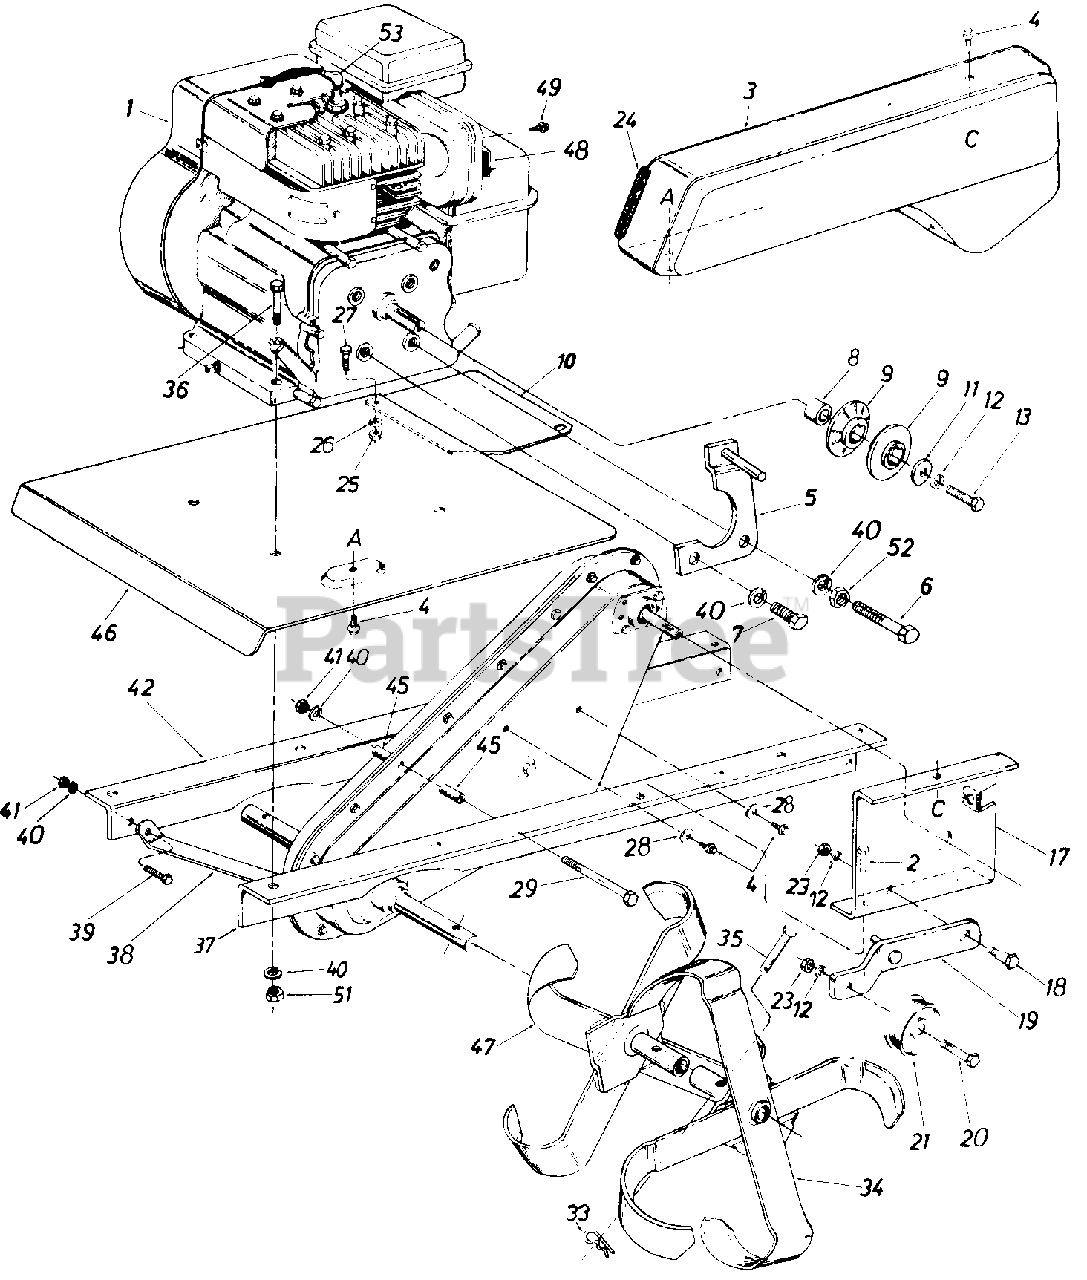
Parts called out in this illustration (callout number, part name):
1	Engine
2	Hex Self-Tap Scr. 5/16-24 x .5"
3	Belt Cover
4	Hex Self-Tap Scr. 1/4-20 x .5"
5	Belt Keeper Brkt. Ass'y.
6	Hex Bolt 5/16-24 x 2.25" Lg. (Gr. 5)
7	Hex Bolt 5/16-24 x .62" Lg. (Gr. 5)
10	Tine Shield Extension
11	Fl-Wash. 318" I.D. x 1.25"
12	L-Wash. 318" I.D.*
13	Hex Bolt 3/8-24 x 1.00" Lg.
17	Idler Mounting Brkt.
18	Shld. Bolt
19	Idler Bracket Ass'y.
20	Hex Bolt 3/8-16 x 1.5" Lg.
21	Idler Pulley
23	Hex Jam Nut 3/8-16 Thd.
24	Trim Strip-3"
25	Hex Nut 1/4-20 Thd.
26	L-Wash. 1/4" I.D.
27	Hex Bolt 1/4-20 x .62 Lg.*
28	Bell-Wash. .26 I.D. x .75 O.D.
29	Hex Bolt 5/16-18 x 3" Lg.*
33	Hairpin Cotter
34	See Tine Chart
36	Hex Bolt 5/16-18 x 1.5" Lg.*
37	Frame Rail-L.H.
38	Front Brace Brkt.
39	Hex Bolt 5/16-18 x .75" Lg.*
40	L-Wash. 5/16" I.D.*
41	Hex Cent. L-Nut 5/16-18 Thd.
42	Frame Rail-R.H.
47	See Tine Chart
49	Hex Self-Tap Scr. #8-32 x .38"
51	Hex Nut 5/16-18 Thd.*
52	Hex Nut 5/16-24 Thd.*
53	Spark Plug Boot
